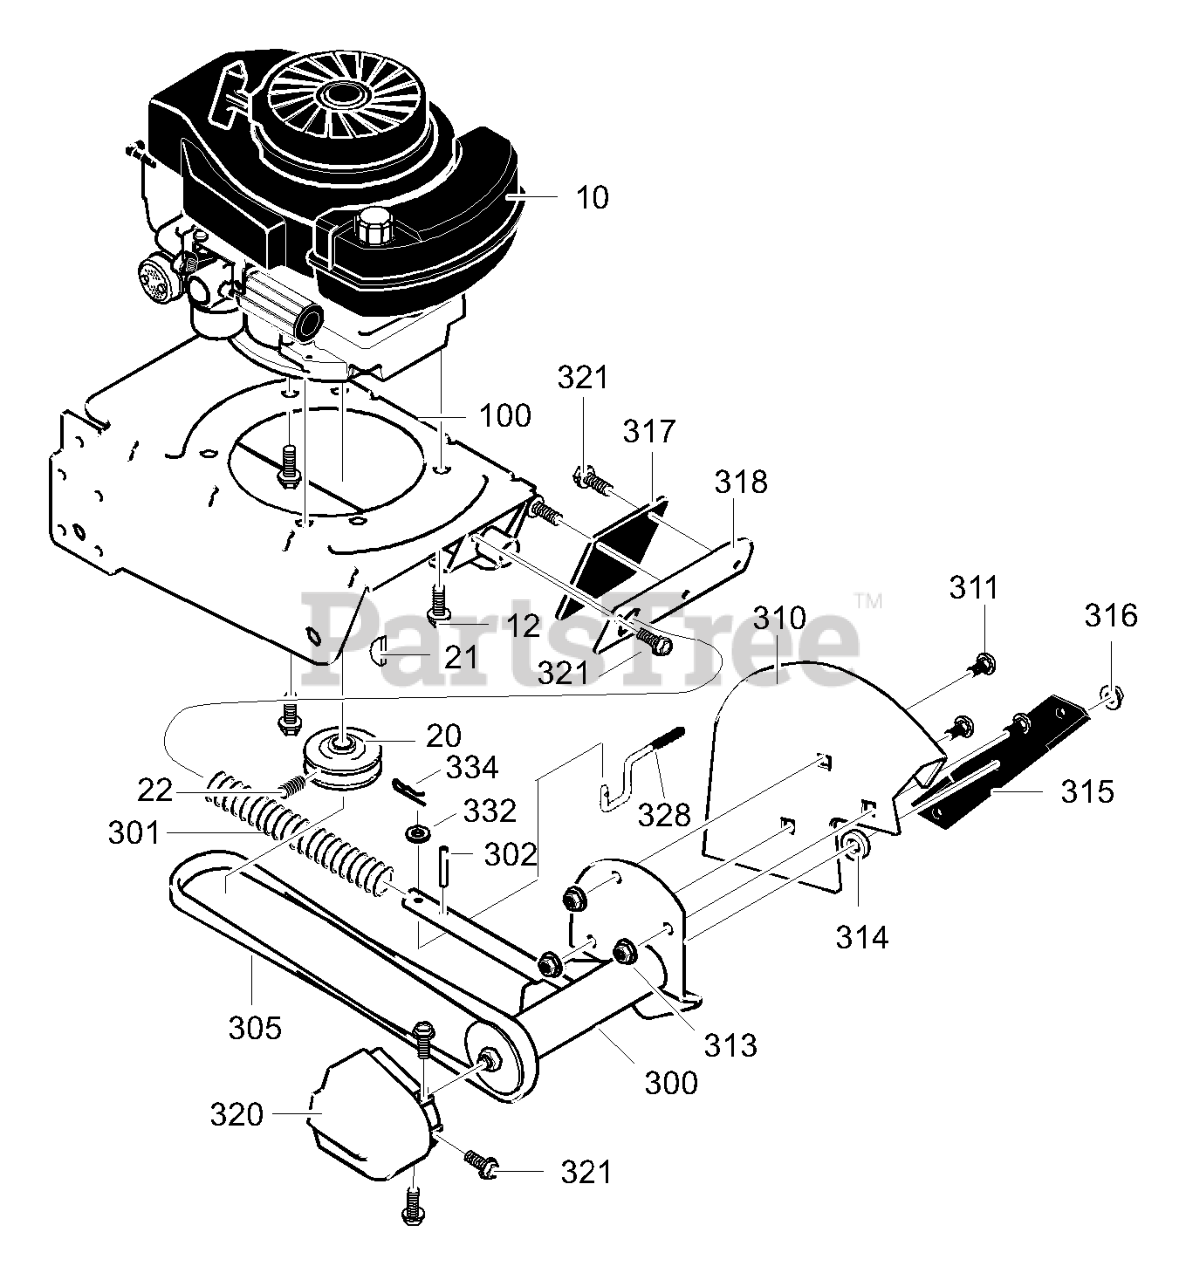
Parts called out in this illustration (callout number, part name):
10	Engine
20	Pulley, V3L
21	Key, Hi Pro #505
22	Screw, Set
100	Frame, Edger
300	Quill Assembly
302	Spring Pin
305	Belt, V4L
310	Blade Guard
311	Bolt, Carriage
313	Nut, 5/16-18
314	Flat washer
315	Blade, Edger
316	Nut, 1/2-20
317	Deflector, Rubber
318	Plate, Rubber Flap
320	Belt Guard
321	Screw, 10-16x.50
328	Lever, Blade
332	Washer
334	Pin, Hair
